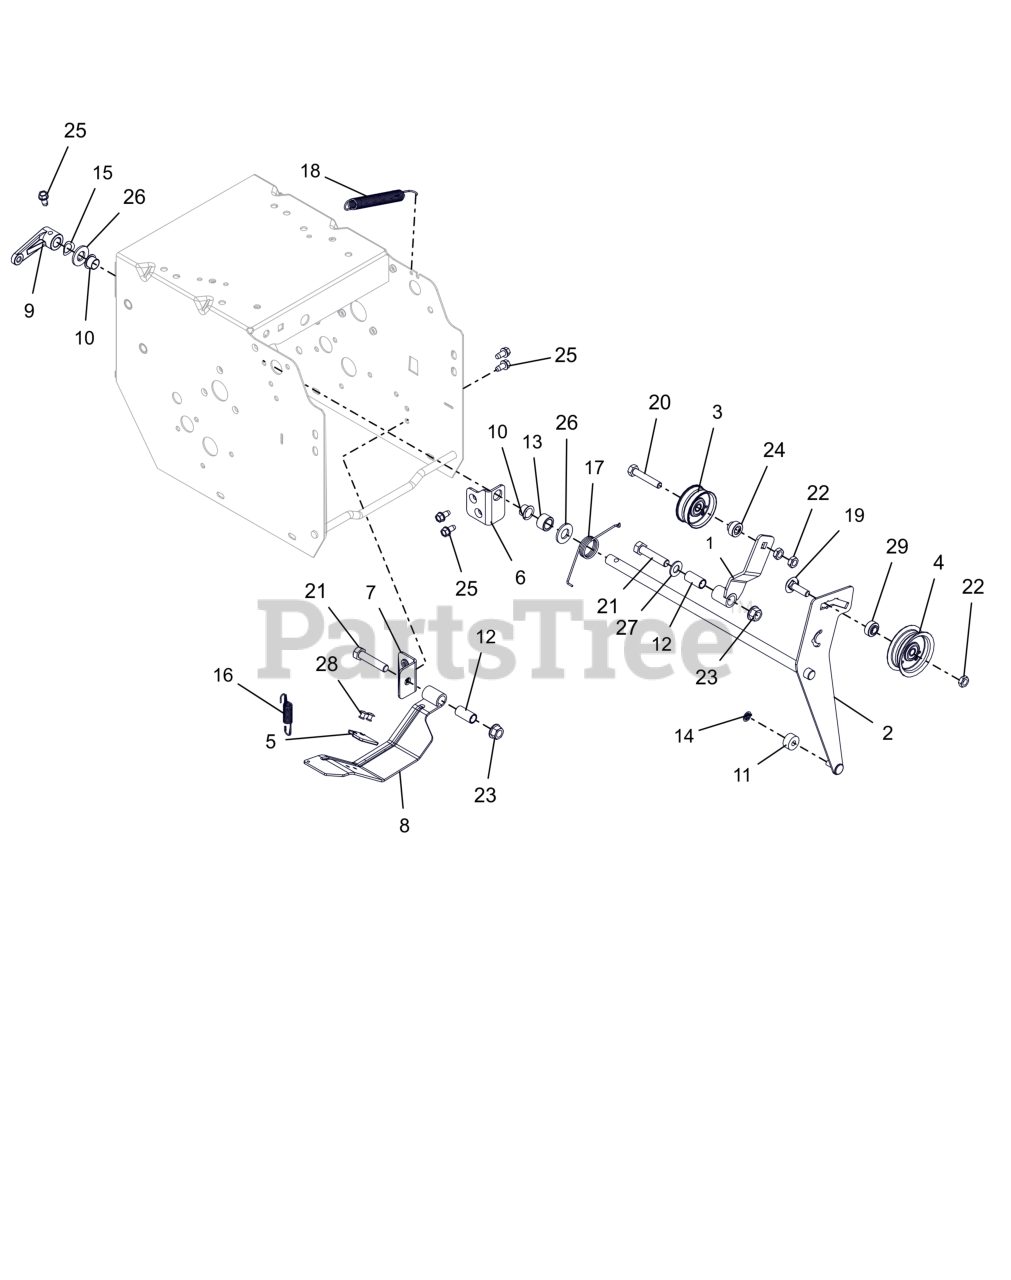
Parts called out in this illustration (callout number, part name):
1	ARM, TRACTION IDLER
2	WELDMENT, ATTACHMENT IDLER ARM
3	IDLER, FLAT - 1.875"
4	IDLER, FLAT - 2.00"
5	PAD, BRAKE
6	BRACKET, MOUNT - IDLER ARM
7	BRACKET, MOUNT - BRAKE
8	BRAKE ARM W/PAD
9	ARM, CLUTCH - ATTACHMENT
10	BUSHING, POLYLINER-.50 SPLIT
11	BSHG,SLV .265 X .625 X .375
12	BSHG-SLV .385X.500X1.045
13	BSHG-SLV .510X.751X.475
14	RG-RTNG-EXT .250X.010
15	WSHR-WAVE .50X.75X.015 .13FRHT
16	SPRING-EXT .437 X .438 X 2.64
17	SG-TORS .075 X .955
18	SPRING, EXTENSION
19	BLT, RHSSN .31-18X1.125 G5 ZCC
20	BLT, HEX .31-18X1.75 G5 ZCC
21	BLT, HEX .38-16X1.75 G5 ZCC
22	NUT-LK-CTR-JAM .312-18 GB ZCC
23	NUT-LK-TOP-FLG .38-16 ZC120
24	SPCR, BRG .315X.500X.481X.281
25	SCR-TAP .25-20X.50 HWH ZCC
26	WSHR,FLT .531X1.062X.095 ZCC
27	WSHR,FLT .406X.812X.065 ZCC
28	RVT, POP .1875 ZCC
29	SPCR, BRG .315X.500X.358X.281
